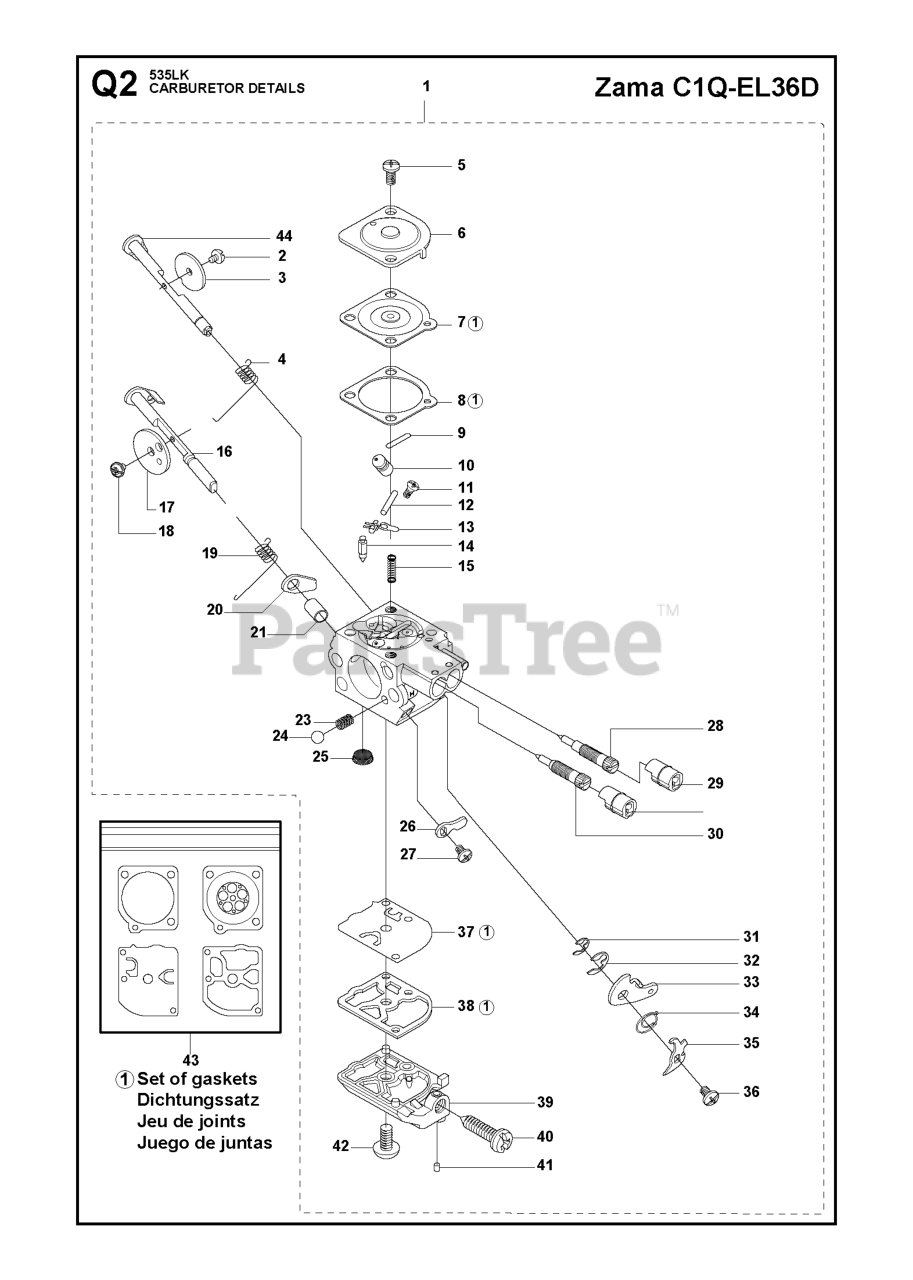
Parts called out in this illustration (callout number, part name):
1	CARBURETTOR
4	RETURN SPRING
10	MAIN NOZZLE
12	PIN RETAINING SCREW
14	INLET NEEDLE
16	CHOKE SHAFT
25	FUEL INLET SCREEN
28	IDLE SCREW
29	LIMITER CAP KIT
30	SCREW MAIN MIXTURE
34	SPRING SPRING THROTTLE RETURN
37	PUMP DIAPHRAGM
43	GASKET KIT (ZAMA GND39)
44	SHAFT ASSY THROTTLE
